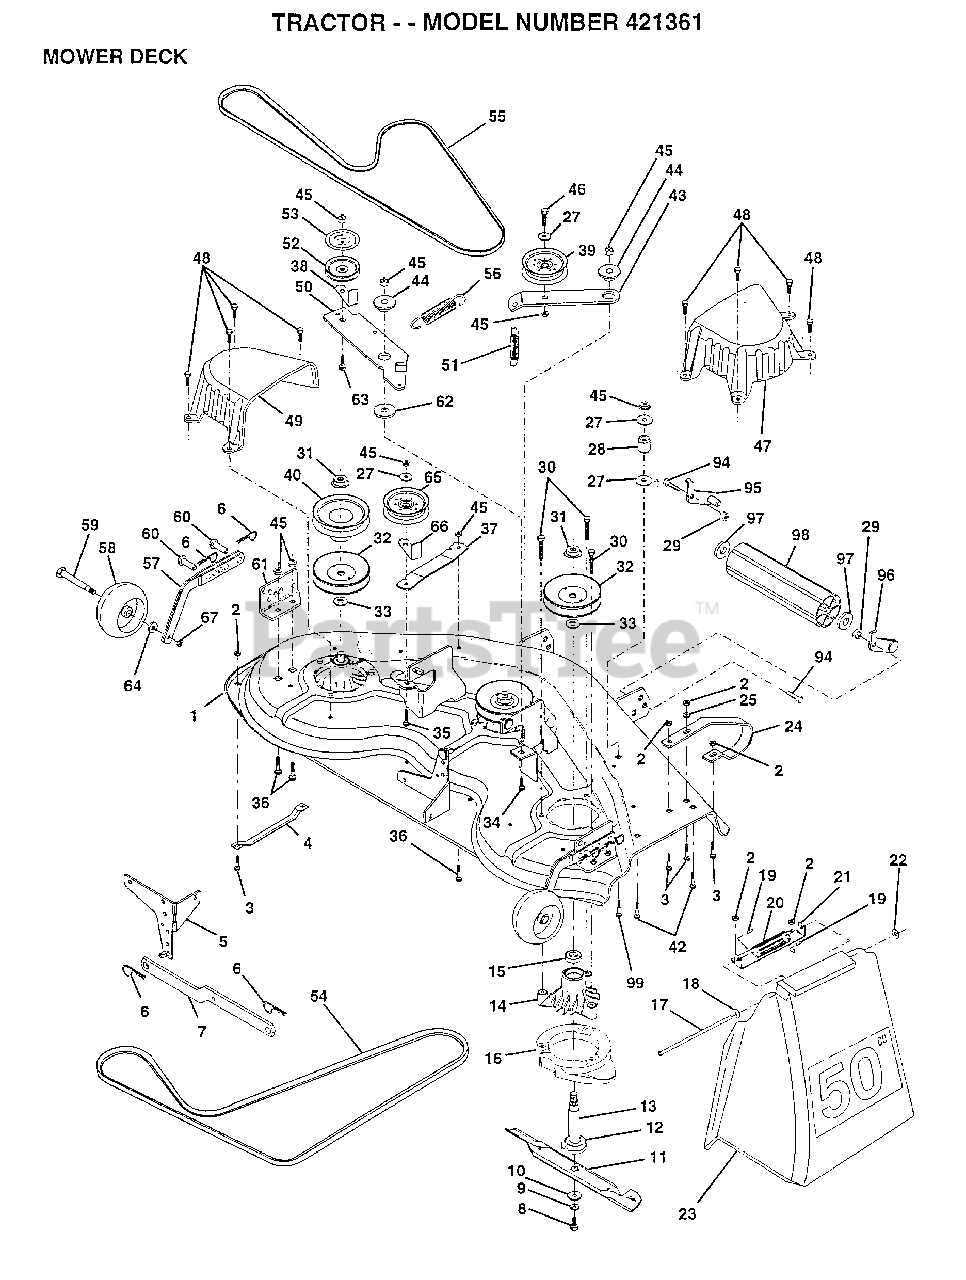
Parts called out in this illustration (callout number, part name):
1	DECK ASM MWR 50VT
4	RUNNER-LH M
5	BRKT.ASM.SW.44/50
8	BLADE BOLT
10	WASHER.HARD.BLADE
11	"BLADE.50"" HD"
12	BEARING.BALL
14	HOUSING.MAND.44.V
15	BEARING
16	STRIPPER RND MWR
17	ROD-HINGE T
18	WASHER
19	SHAFT.ASM.W/BRNG
19	CAP-SLEEVE LT
20	SPRING TORSION
21	BRKT DEFLECTOR
22	NUT PUSH M
23	DEFLECTOR
24	"RUNNER RH 50"" DK"
25	WASHER M
27	WASHER
29	NUT
33	WASHER
34	BOLT.3/8-14X1.25
35	BOLT
36	BOLT D
37	STIFFENER.ARM.IDL
39	FLAT IDLER PULLEY
40	"PULLEY.DRIVEN.44"""
42	BOLT
43	"ARM.IDLER.SEC.44"""
44	SPACER RETAINER
47	"COVER.MAND.RH.44"""
48	SCREW.1/4-20X5/8
49	COVER.MANDREL.LH
50	ARM.IDLER.PRIMARY
51	"SPRING.SEC.44""VEN"
52	PULLEY.IDLER.VGRO
53	SHIELD.IDLER.44.V
54	BELT V PRIM 50
55	BELT-V.SEC.46.KEL
56	SPRING.EXT.DECK.
57	BAR.ASM.GUAGE.WHL
58	WHEEL.GUAGE.MED.
59	BOLT.SHOULDER
60	PIN.CLEVIS
61	BRACKET.GUAGE.WHL
62	HARDENED WASHER
63	BOLT.3/8-16X1.50
64	WASHER
65	IDLER-FLAT T
67	LOCKNUT
94	BOLT
97	WASHER
99	BOLT
